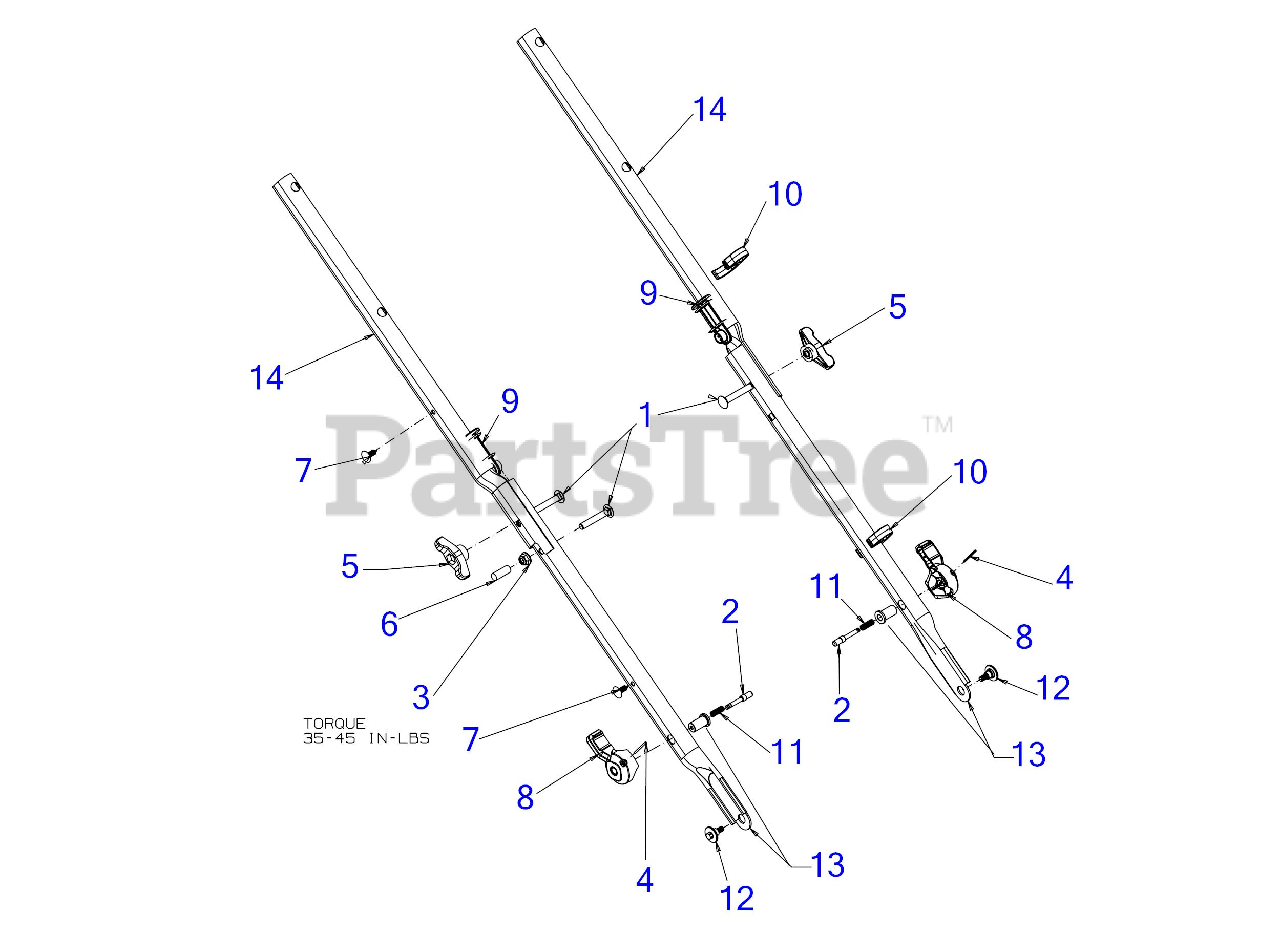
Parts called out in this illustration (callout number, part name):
1	BOLT 5/16-18 x 2.00 GR5
2	HANDLE ADJUSTMENT PIN
3	FLANGE LOCK NUT 5/16-18
4	SPLIT ROLL PIN 5/64 X 1.38
5	WING KNOB 5/16-18
7	RATCHET CLIP .250
8	HANDLE LEVER KNOB
9	HANDLE END PLUG
10	CABLE CLIP CORE
11	COMPRESSION SPRING
12	SHOULDER SCREW .500 X.118X1/4-20
13	LOWER HANDLE
14	UPPER HANDLE
